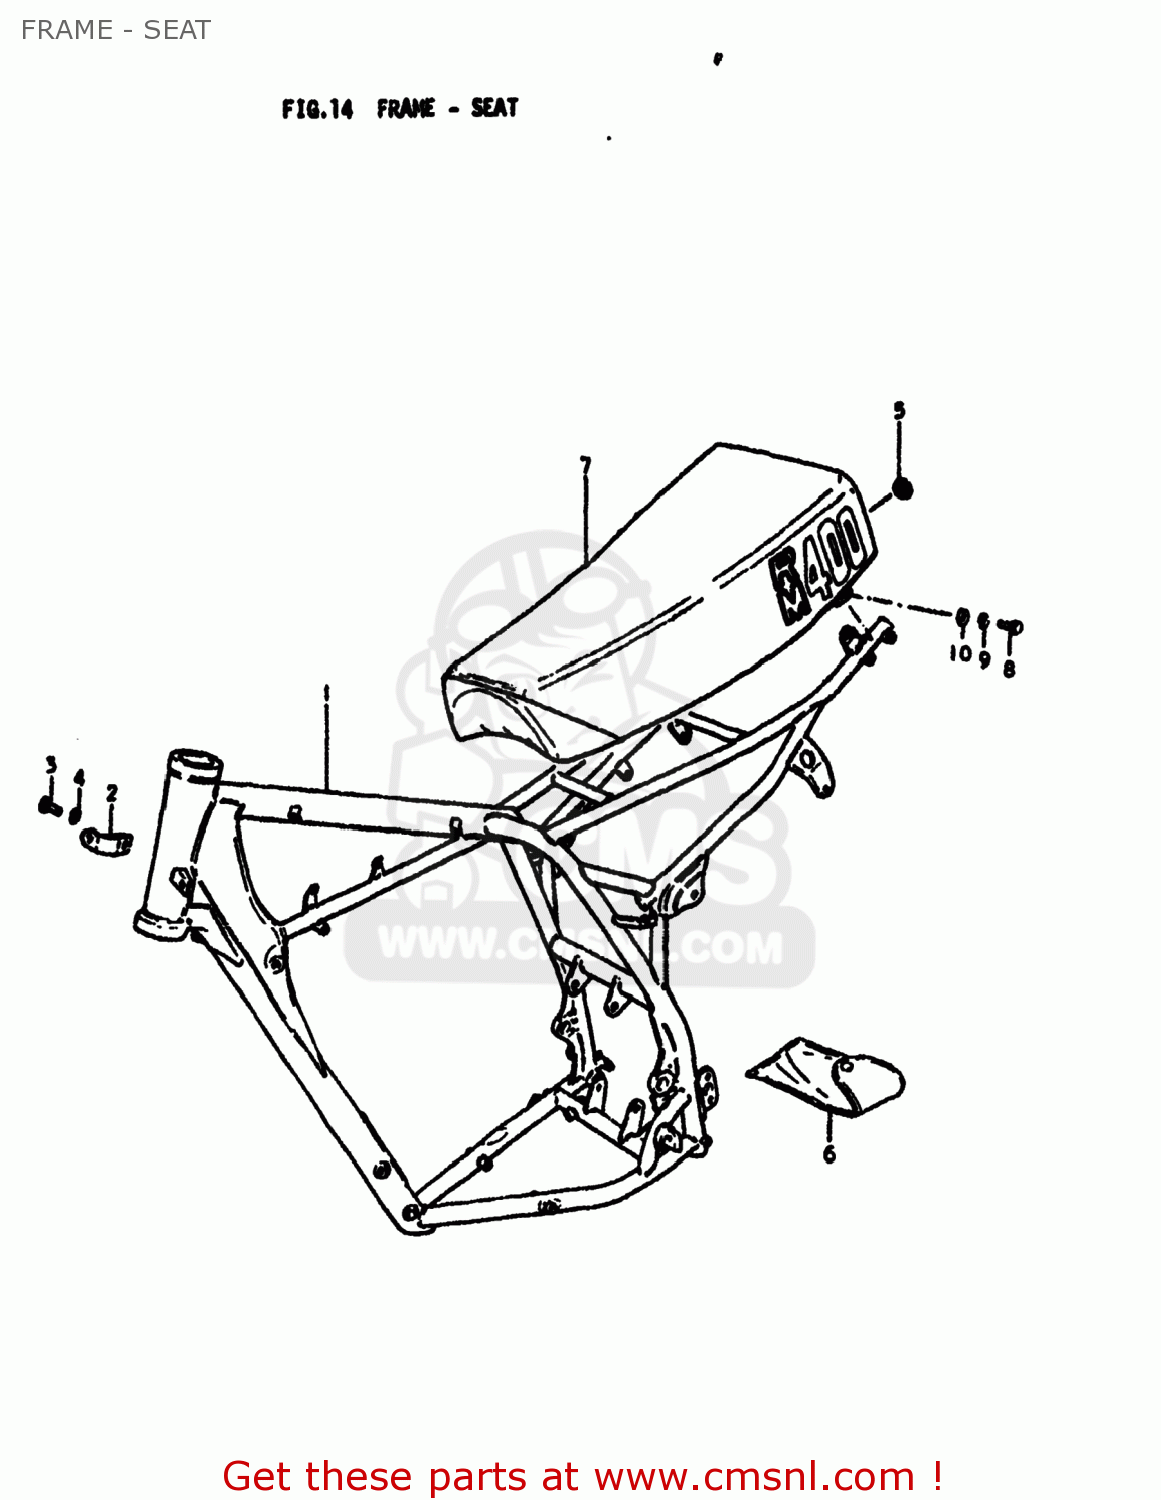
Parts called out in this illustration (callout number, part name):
1	FRAME
2	PLATE,ENGINE MOUNTING
3	BOLT
4	LOCK WASHER
5	PLUG(OD:19)
6	TOOL SET
7	SEAT ASSEMBLY
8	BOLT, UPPER
9	LOCK WASHER
10	WASHER(6.5X18X1)
